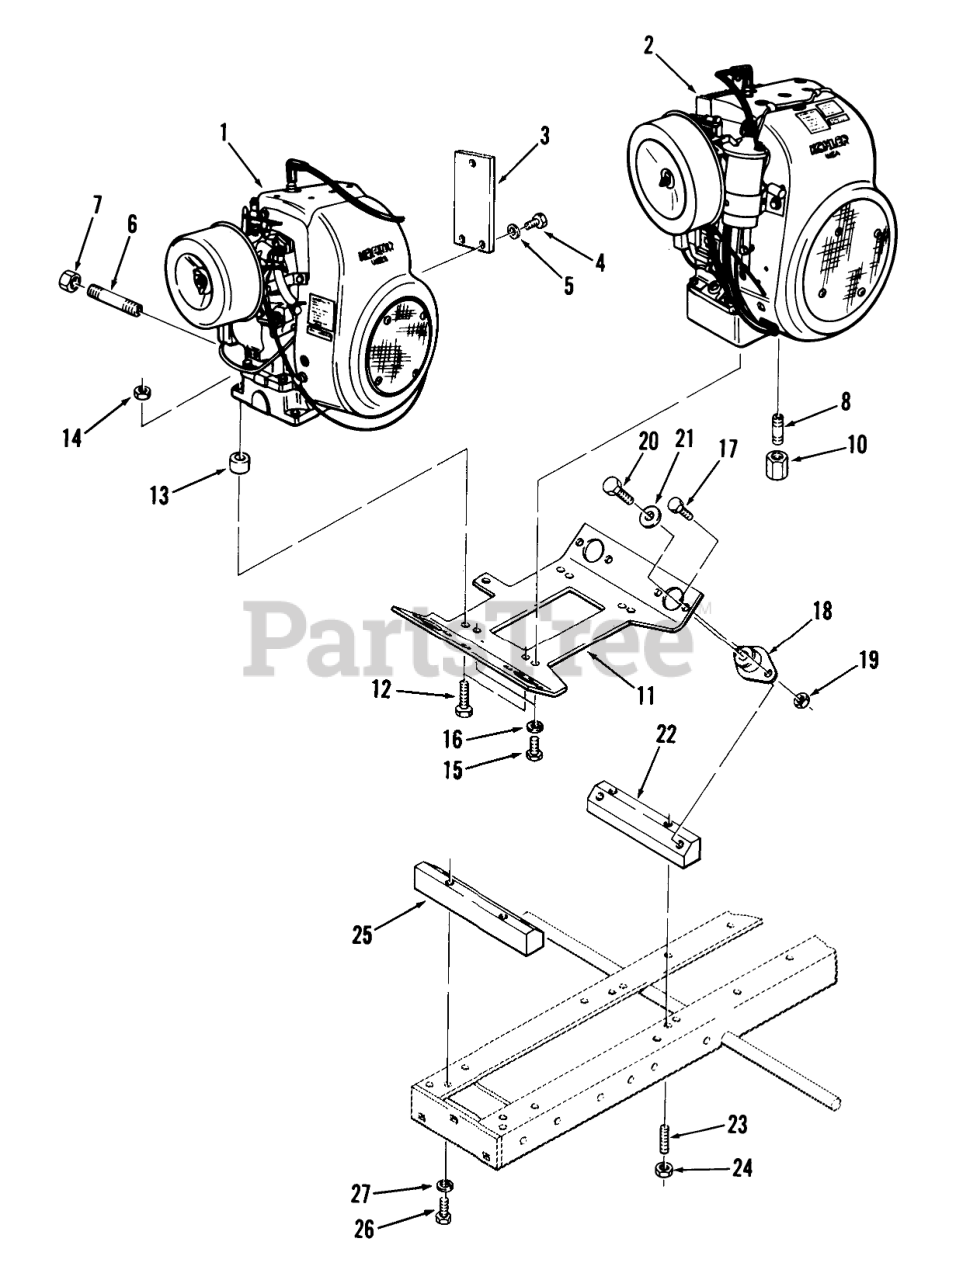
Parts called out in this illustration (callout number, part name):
1	Engine-8HP Kohler K-1815 Spec PS-30743D
2	Engine-12HP Kohler K-301AS Spec PS-47723D
2	Engine-12 HP Kohler K-301AS Spec 47742
2	Engine-14HP Kohler K-321AS Spec PS-60362D
2	Engine-14 HP Kohler K-321AS Spec 60373
2	Engine-16HP Kohler K-341AS Spec PS-71303D
2	Engine-16 HP Kohler K-341AS Spec 71311
2	Engine-10 HP Kohler K-241AS Spec 46812
3	PLATE COIL & SOL MTG
4	BOLT
5	LOCKWASHER
6	Nipple 1/2"
7	CAP-PIPE 1/2 IN
8	Pipe Nipple 1/4 C-101, C-121, C-141, C-161 Only
10	CAP 1/4 PIPE
11	Engine Cradle
12	Bolt
13	SPACER
14	Nut
15	Bolt
16	LOCKWASHER
17	H H C S
18	MOUNT-ISOLATION
18	Isolation Mount C-85
19	Nut
20	Bolt
21	Washer
22	MOUNT-BLOCK-REAR
23	SET SRW 3/8X16-1 3/4
24	Nut
25	Engine Mounting Block-Front
26	BOLT
27	LOCKWASHER
